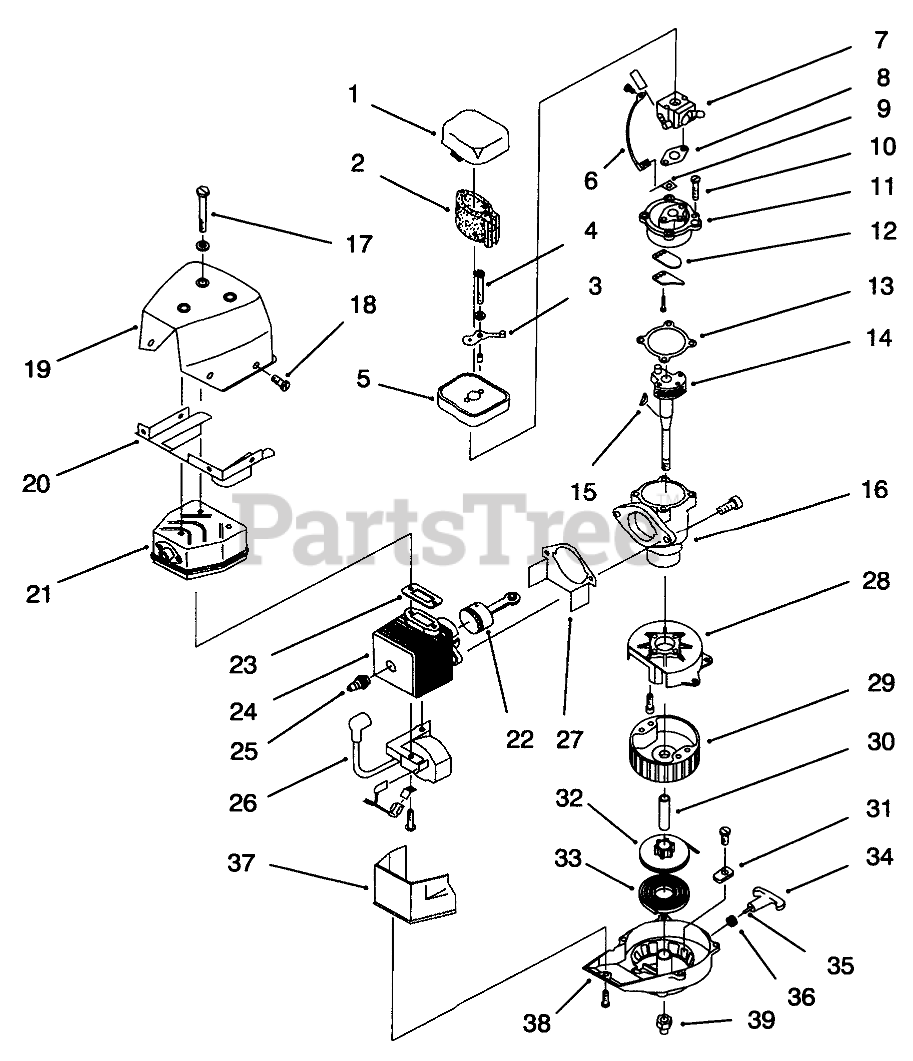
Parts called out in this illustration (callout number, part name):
1	AIR CLEANER COVER ASM
2	AIR CLEANER FILTER
3	CHOKE LEVER ASM
4	ASSEMBLY - MOUNTING BOLT
5	BASE - AIR CLEANER
6	LEAD - WIRE
7	Carburetor
8	CARBURETOR GASKET(10 PER PACK)
9	GROUND TAB
10	Reed Plate Mounting Screw
11	CARB MNT & GASKET AY
12	Reed Asm.
13	CARB MT GASKET (10-PK)
14	ASSEMBLY - CRANK SHAFT
15	FLYWHEEL KEY (10-PK)
16	Crankcase Service Asm. (Incl. Ref. #10, 13-16)
17	MUFFLER MTG BOLT ASM
18	ASSEMBLY - MOUNTING SCREW
19	SHIELD - UPPER HEAT
20	SHIELD LOWER HEAT
21	ASSEMBLY - MUFFLER
22	PISTON & ROD ASM
23	Exhaust Gasket
24	ASSEMBLY - CYLINDER
25	SPARK PLUG
26	Module Asm.
27	GASKET - CYLINDER
28	Shroud Asm.
29	FLYWHEEL
30	SPACER
31	Pulley Retainer Asm.
32	RECOIL PULLEY ASM
33	RECOIL SPRING
34	Handle-Pull
36	ROPE GUIDE
37	SHROUD - EXTENSION
38	STARTER HSG ASM
39	ASM - CRANKSHAFT
